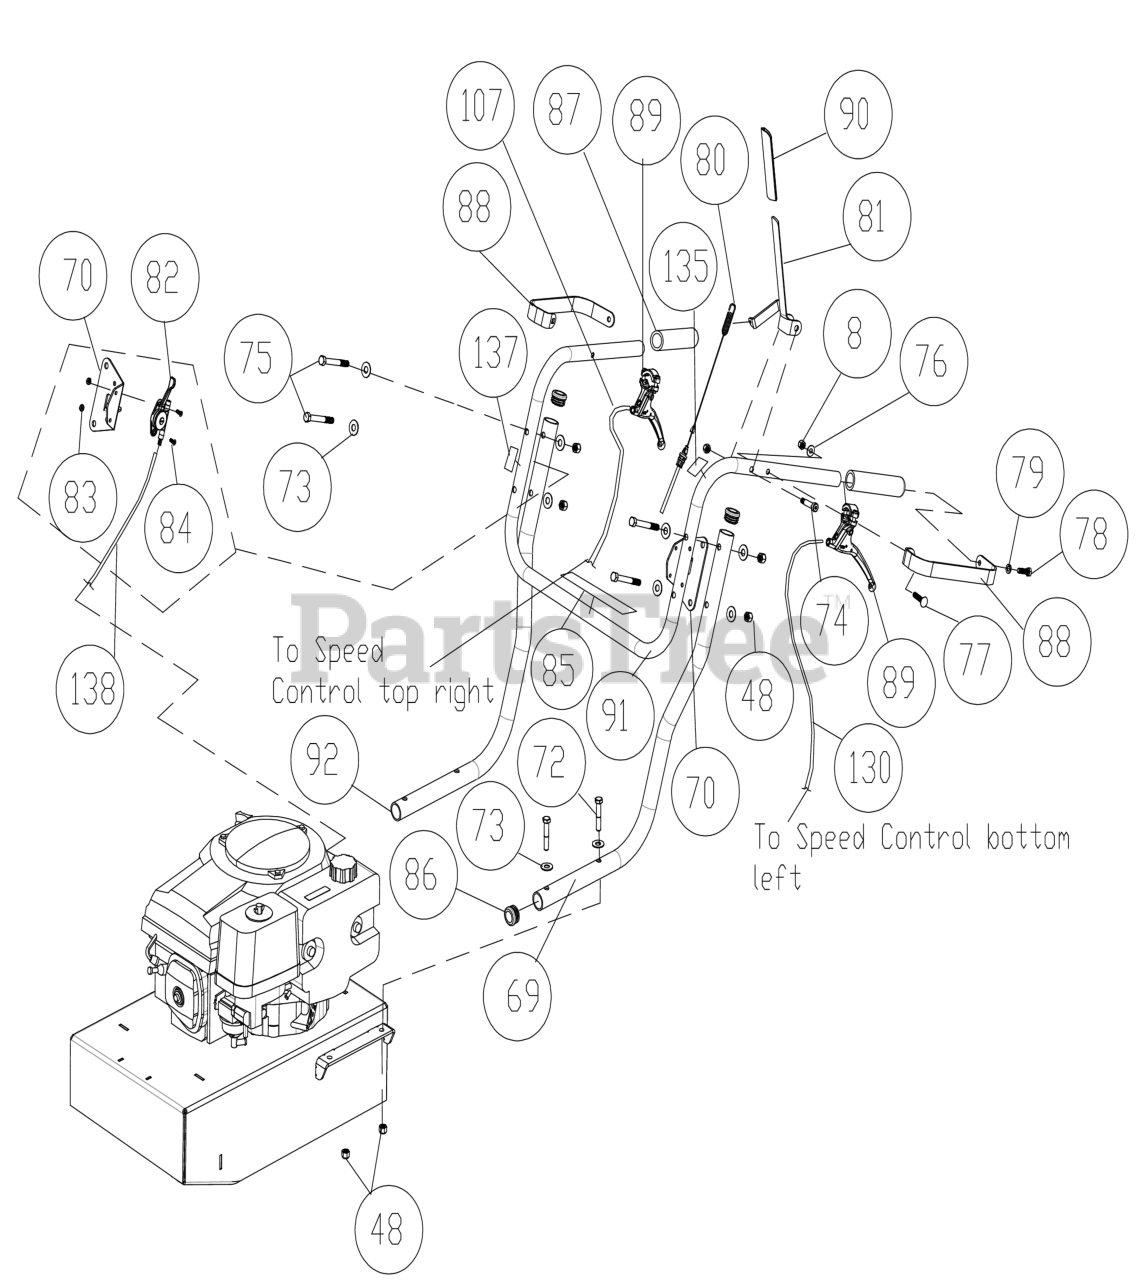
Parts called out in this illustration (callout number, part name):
8	NUT LOCK 5/16"-18 HEX Z/P
48	NUT LOCK 3/8"-16 HEX
69	HANDLE, LOWER LEFT PAINTED
70	BRACKET THROTTLE BC26
72	SCREWCAP 3/8"-16X2" HCS ZP
73	WASHER 3/8"FC7/16"X1"X5/64"
74	BOLT SHOULDER 3/8 X 1 1/2"
75	SCREWCAP 3/8"-16X3" HCS ZP
76	WASHER 1/4" FLAT Z/P
77	BOLT CARRIAGE 5/16"-18X1 1/2" ZP
78	SCREWCAP 5/16"-18 X 1" HCS ZP
79	WASHER LOCK 5/16 ST MED
80	CABLE CLUTCH
81	SEE: 500312-S
82	CONTROL THROTTLE BLOWER
83	NUT LOCK LT #10-24 HEX
84	SCREW MACHINE FLAT HD PHIL #10-24
85	LABEL DRIVE DIRECTION
86	PLUG TUBE INSERT 1.25" O.D.
87	GRIP HANDLE
88	GUARD HAND BC2600
89	CONTROL MAGURA
90	GRIP LEVER 0.125" X 1" X 5" ORANGE
91	HANDLE UPPER WITH GRIPS & LABELS BC 26 HYDRO
92	HANDLE LOWER RIGHT
107	CABLE SPEED CONTROL RT
130	CABLE SPEED CONTROL LFT
135	LABEL CLUTCH BLADE
137	LABEL THROTTLE BC
138	CABLE THROTTLE BLOWER
